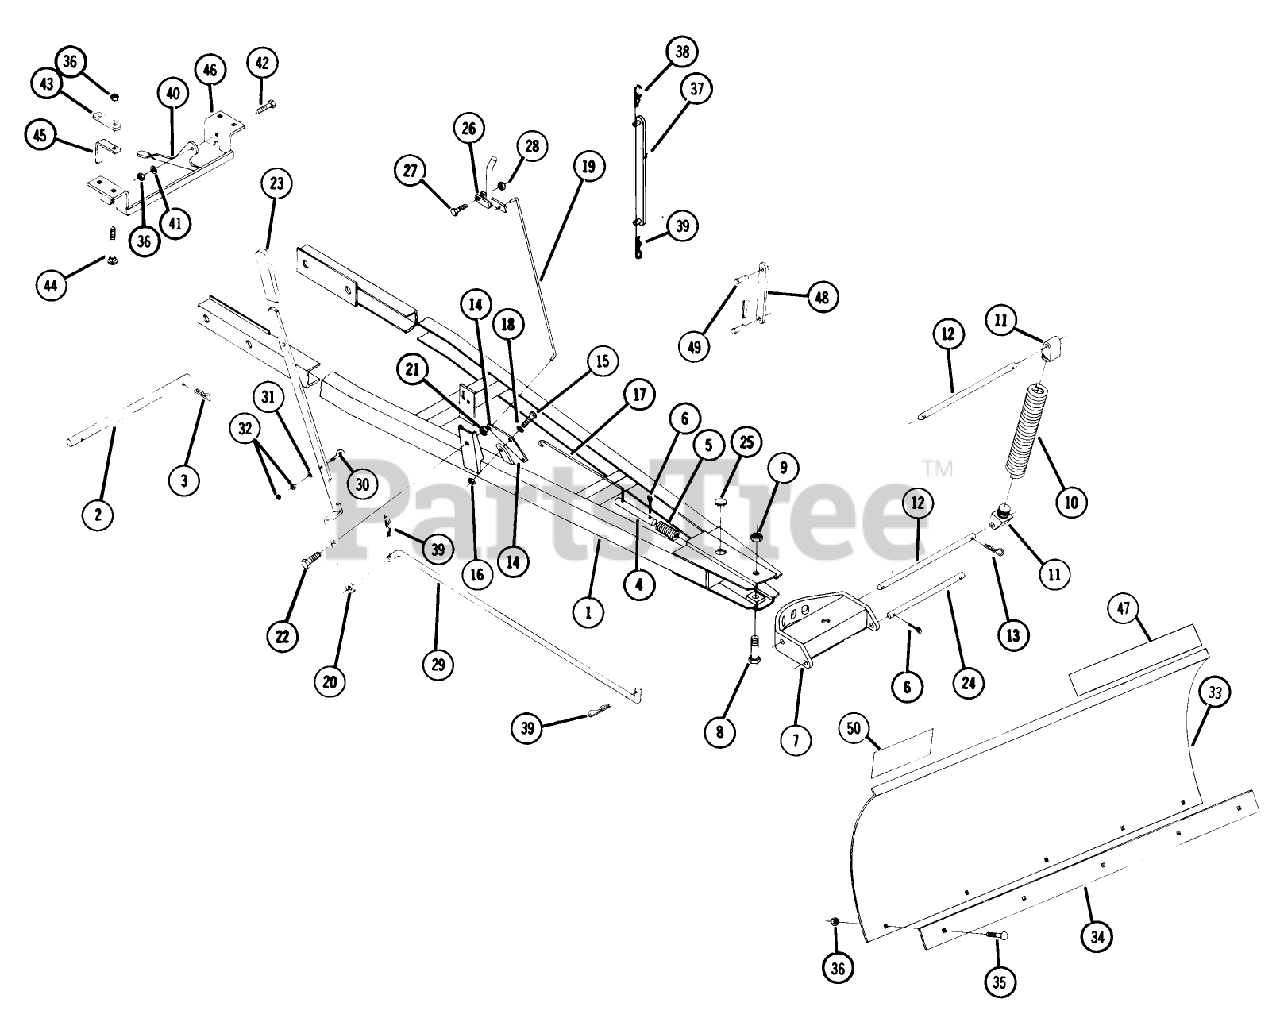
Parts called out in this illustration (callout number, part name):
1	Ass-y. Frame
2	Mounting Shaft
3	Hairpin
4	Index Pin
5	SPRING-COMPRESSION
7	Sector and Channel
8	Bolt
9	Nut
10	Spring
11	Lug
12	ROD-PIVOT, BLADE
13	Hairpin
14	Index Plate
15	BOLT
16	NUT
17	Head-Cylinder
18	Washer
19	UPPER INDEX ROD
20	Index Lever
21	Jam Nut
22	Bolt
23	GRIP
24	ROD-LOWER
25	PLUG
26	INDEX LEVER
27	Bolt
28	Nut
30	Eye Bolt
31	Lockwasher
32	Hex Nut
33	Blade
34	Plate
35	Bolt-Carriage
36	NUT
37	LIFT BAR ASSY R
38	Hairpin Cotter
39	Hairpin
40	PLATE-LATCHING
41	Washer
42	BOLT
43	BRACKET-REAR LINK MOUNTING
44	Bolt-Carriage
45	SPACER-BRACKET
46	Bracket
47	DECAL-WHEEL HORSE
48	LINK-LIFT
49	Pin
50	Caution Decal
